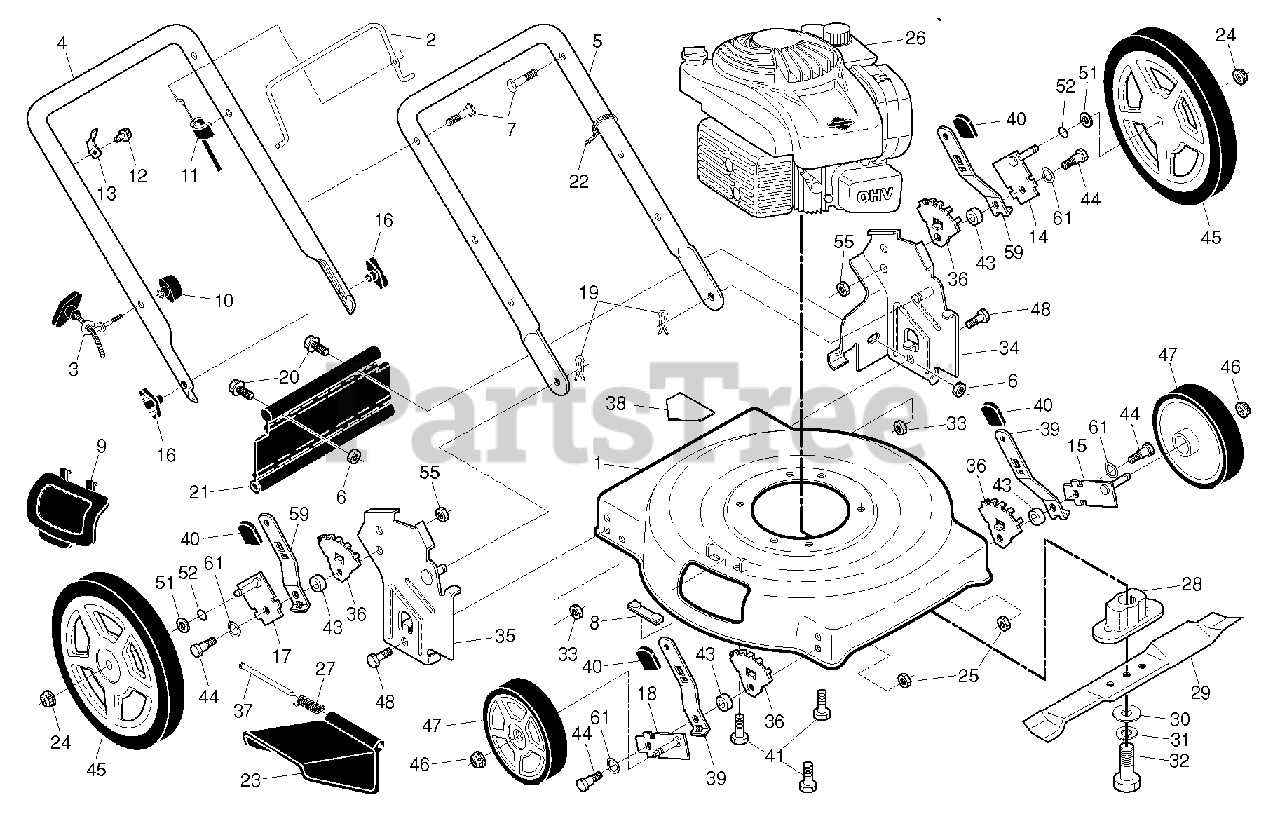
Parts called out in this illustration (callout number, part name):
1	HOUSING.22SD.ECON.PUSH.YELLOW
2	BAIL.CONT.D.STRAIGHT.PUSH.YELL
3	Rope Guide, Blk Zinc Chrom
4	HANDLE.UPPER.ECONOMY.BLACK
5	HANDLE.LOWER.D-STRAIT.BLACK
6	LOCKNUT.NYLOC.1/4-20
7	BOLT, HANDLE 5/16-18X1.75
8	CLIP. CLOSEOUT
9	PLATE.MULCHER.22.ECON.BLACK
10	T-KNOB.NEW ROPE GUIDE
11	CABLE.MZR.RATO.22"LOW.
13	BRACKET.UPSTOP.RT
14	Axle Arm Assembly, .Lr.5/9.Pos.Bzp
15	AXLE ARM ASSY FRONT LH
17	Axle Arm Assembly, RR 5/9 Pos BZP
18	AXLE ARM ASSY FRONT RH
19	HAIRPIN COTTER
20	BOLT.HEX.1/4.X.3/4.DICHROMATE
21	SKIRT.REAR.22RD/SD.FO/VE
22	TIE GUIDE
23	GUARD.DISCHARGE.22".
24	NUT.HEX.FLANGE.3/8-16.LOCKNUT
25	NUT.FLANGE.HEX.5/16X18.BLACK
27	SPRING.HINGE
28	ADAPTOR.BLADE.7/8
29	BLADE.22.MULCH.STANDARD
30	WASHER,HARDEN
32	SCREW, HEX HD 3/8-24 X 1-3/8
33	NUT.71038.31-18.HEX.NYLOCK
34	BRKT.ASM.HDL.22.ECON.BLACK
35	BRKT.ASM.HNDL.22.ECON.HW.RH.BL
36	WHEEL ADJ BRACKET FRONT
37	HINGE ROD
38	DECAL.INTERNATIONL.CUTFINGER
39	SELECTOR SPRING, FRONT
40	Knob
41	BOLT 3/8-16X1-1/8
43	SPACER.HEIGHT.ADJUSTER
44	SHOULDER BOLT 5/16-18
45	WHEEL.12X1.75.5SPK.BRK.BLACK
46	NUT.HEX.FLANGE.3/8-16.LOCKNUT
47	WHEEL.7X1.75.5SPK.BRK.BLACK
51	WASHER PM
52	O-RING..070X.487.NEOPRENE
55	NUT.LOCK.5/16-18
59	SPRING.SEL.22.ECON.HI-WHL.RATO
61	WASHER.CURVED.CYLINDRICAL
